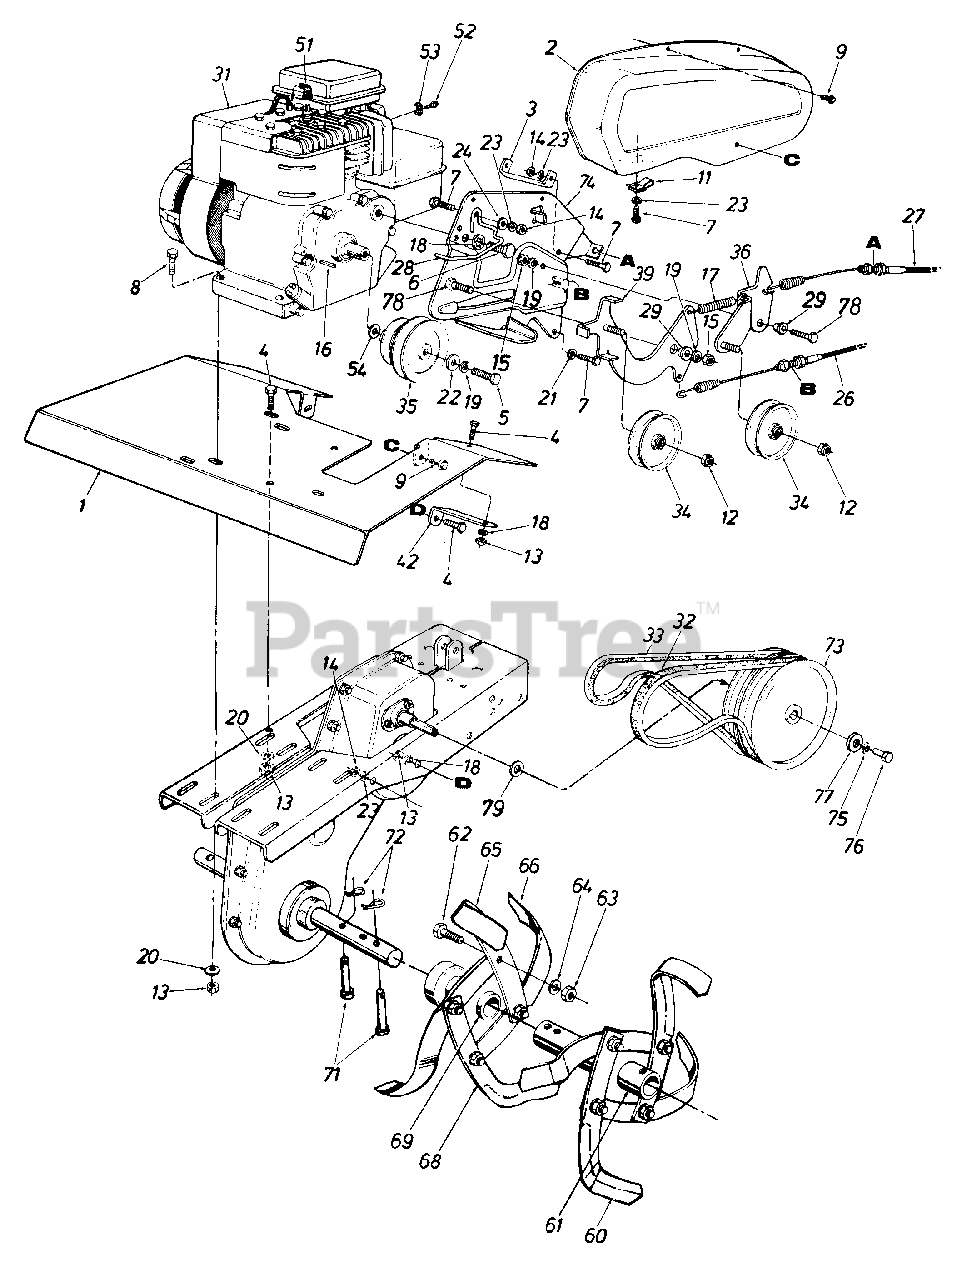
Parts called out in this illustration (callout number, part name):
1	Tine Shield
4	Hex Bolt 5/16-18 x .75" Lg.
5	Hex Bolt 3/8-24 x 1.25" Lg.
6	Hex Bolt 5/16-24 x .62" Lg.
7	Hex Bolt 1/4-20 x .85" Lg.
8	Hex Bolt 5/16-18 x 1.5" Lg.
9	Hex Wash. Hd. Tap Scr. 1/4-20 x .5" Lg.
11	Speed Nut 1/4-20 Thd.
12	Hex L-Nut 3/8-24 Thd.
13	Hex Nut 5/16-18 Thd.
14	Hex Nut 1/4-20 Thd.
15	Hex Nut 3/8-24 Thd.
16	Sq. Key 3/16 x 1.5n Lg.
17	Extension Spring 2.03 Lg.
18	L-Wash. 5/16" I.D.
19	L-Wash. 3/8" I.D.
20	Bell-Wash. 5/16n I.D.
21	Spr. Wash. .265n I.D. x .562" O.D.
22	Fl-Wash. 3/8" I.D. x 1" O.D. x 1.27"
23	L-Wash. 1/4" I.D.
24	Fl-Wash. .25 I.D. x .62 O.D.
26	Clutch Control Cable
27	Clutch Control Cable
28	Belt Guard Rod
29	Shld. Spacer .380 I.D.
31	Engine-B&S 5 H.P.
32	V-Belt
33	V-Belt
34	Fl-Idler w/Flanges 3.12 O.D. x .75
35	Engine Pulley
52	Hex Sems Scr. #10-32 x .62" Lg.
53	Casing Clamp
54	Fl-Wash. .75" I.D. x 1.375" O.D.
60	Outer Tine Ass'y. Comp.-L.H.
61	Outer Tine Adapter Ass'y.
62	Hex Bolt 3/8-24 x 1.25" Lg.
63	Hex Nut 3/8-24 Thd.
64	L-Wash. 3/8" I.D.
69	Inner Tine Adapter Ass'y.
71	Glevis Pin
72	Intern. Cotter Pin
73	Transmission Pulley 6" Dia.
74	Clutch Mtg. Plate Ass'y.
75	L-Wash. 5/16" I.D.
76	Patch Bolt 5/16-18 x 1 " Lg.
77	Fl-Wash. 5/16" I.D.
78	Hex Bolt 3/8-24 x 1.0" Lg. (Grade 5)
79	Fl-Wash. .635" I.D. x 1.25" O.D.
